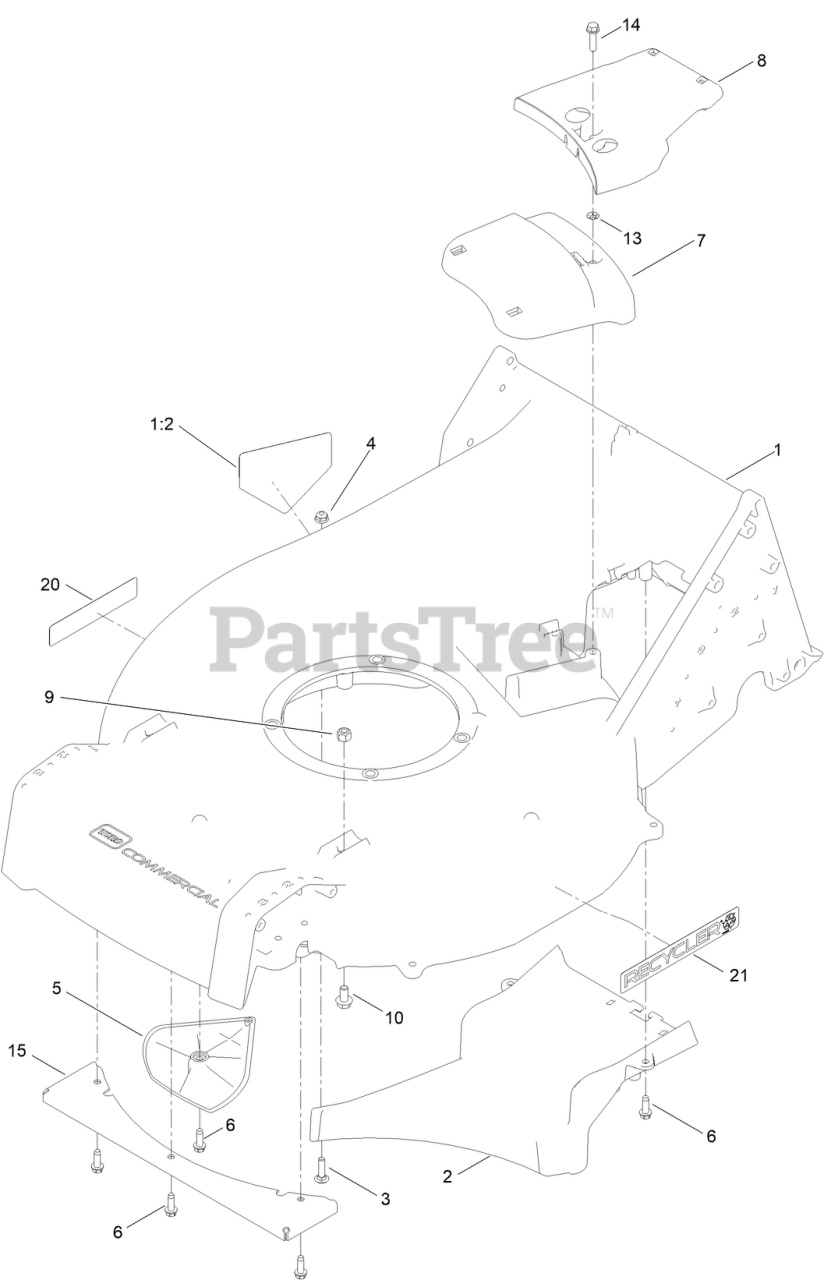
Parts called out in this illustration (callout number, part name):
1	HOUSING ASM
1:2	DECAL-DANGER
2	FLOOR-CHUTE
3	SCREW-CARR
4	NUT-HF
5	KICKER
6	SCREW-HWHTF
7	COVER-BELT, FRONT
8	COVER-BELT, REAR
9	NUT-LOCK, NI
10	SCREW-HHF
13	PUSHNUT-RETAINER, BOLT
14	SCREW-HWHTF
15	GUARD-TOE, FRONT
21	DECAL-RECYCLER
